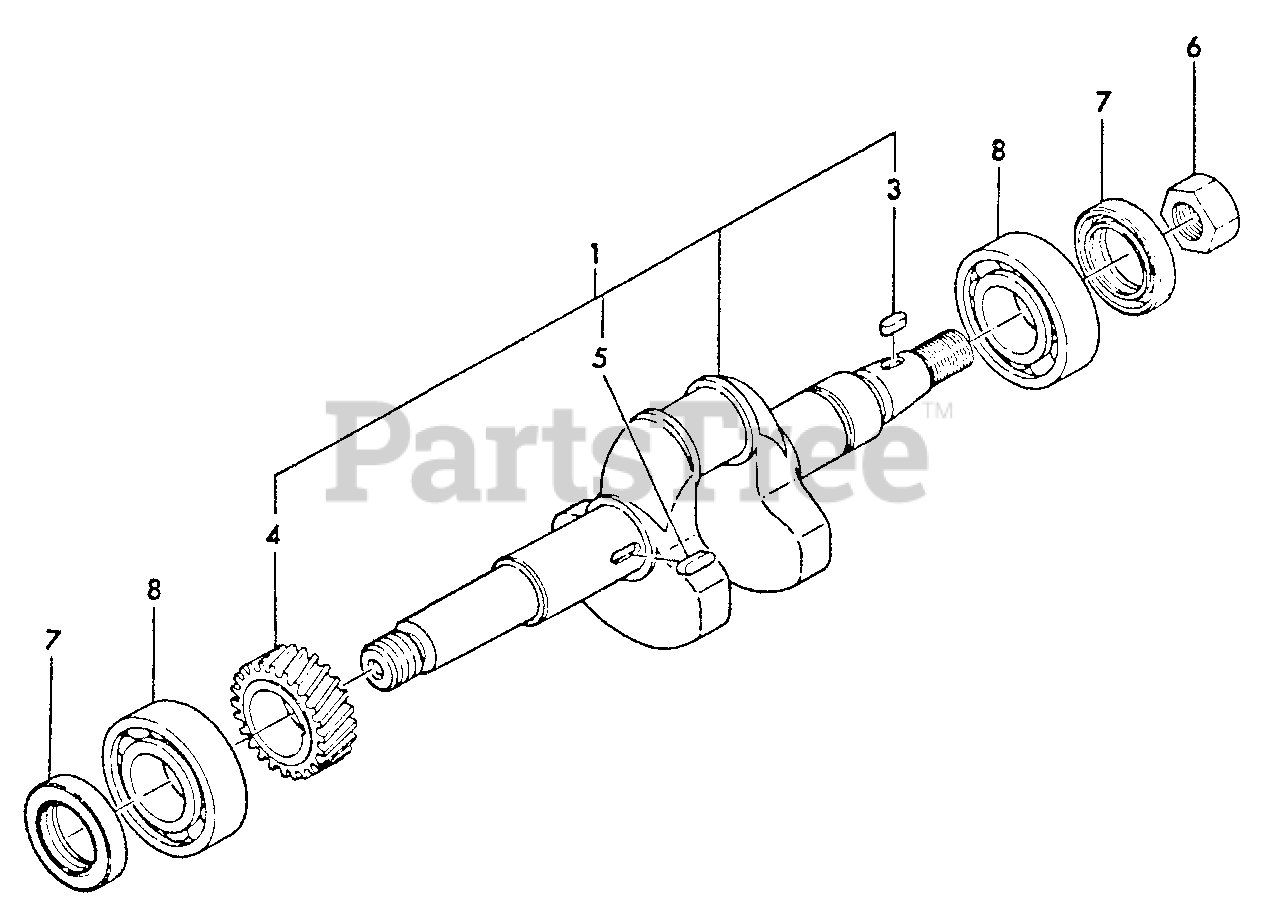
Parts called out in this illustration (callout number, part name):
1	CRANKSHAFT ASSY
3	KEY - 4X10
4	GEAR, CRANKSHAFT
5	KEY - 4X12
6	NUT - 14
7	SEAL, OIL
8	BEARING, BALL - 6205C3
